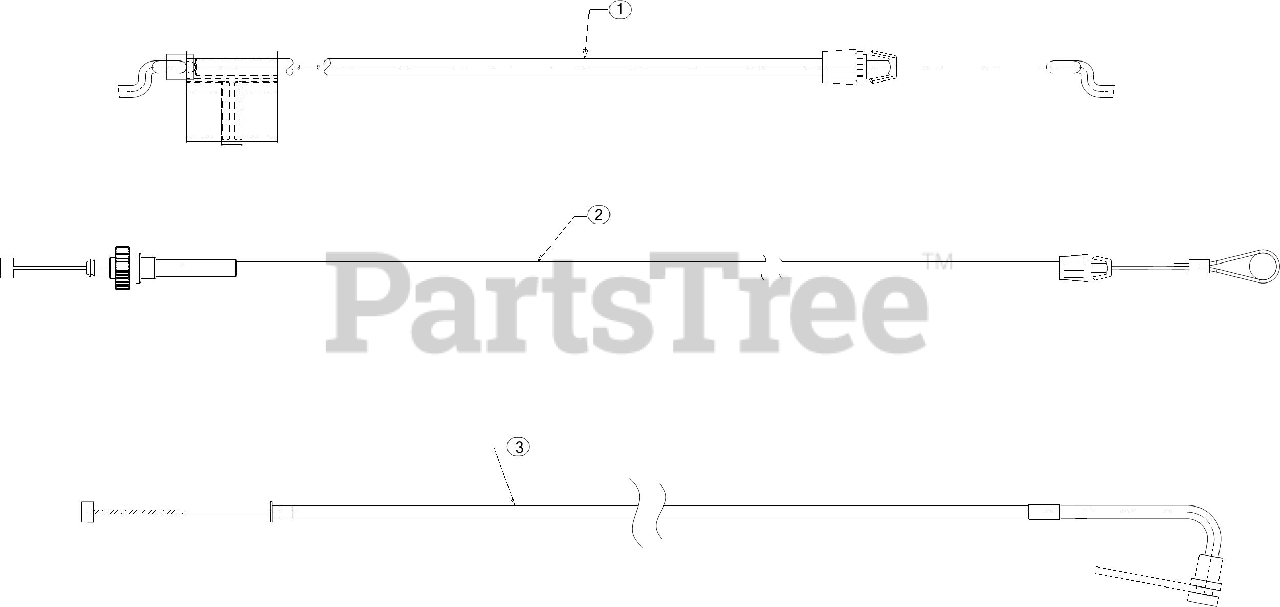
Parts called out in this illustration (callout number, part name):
1	CONTROL CABLE
2	SPEED ADJUSTMENT CABLE 56.25"
3	SPEED SELECT CABLE W/ELBOW
